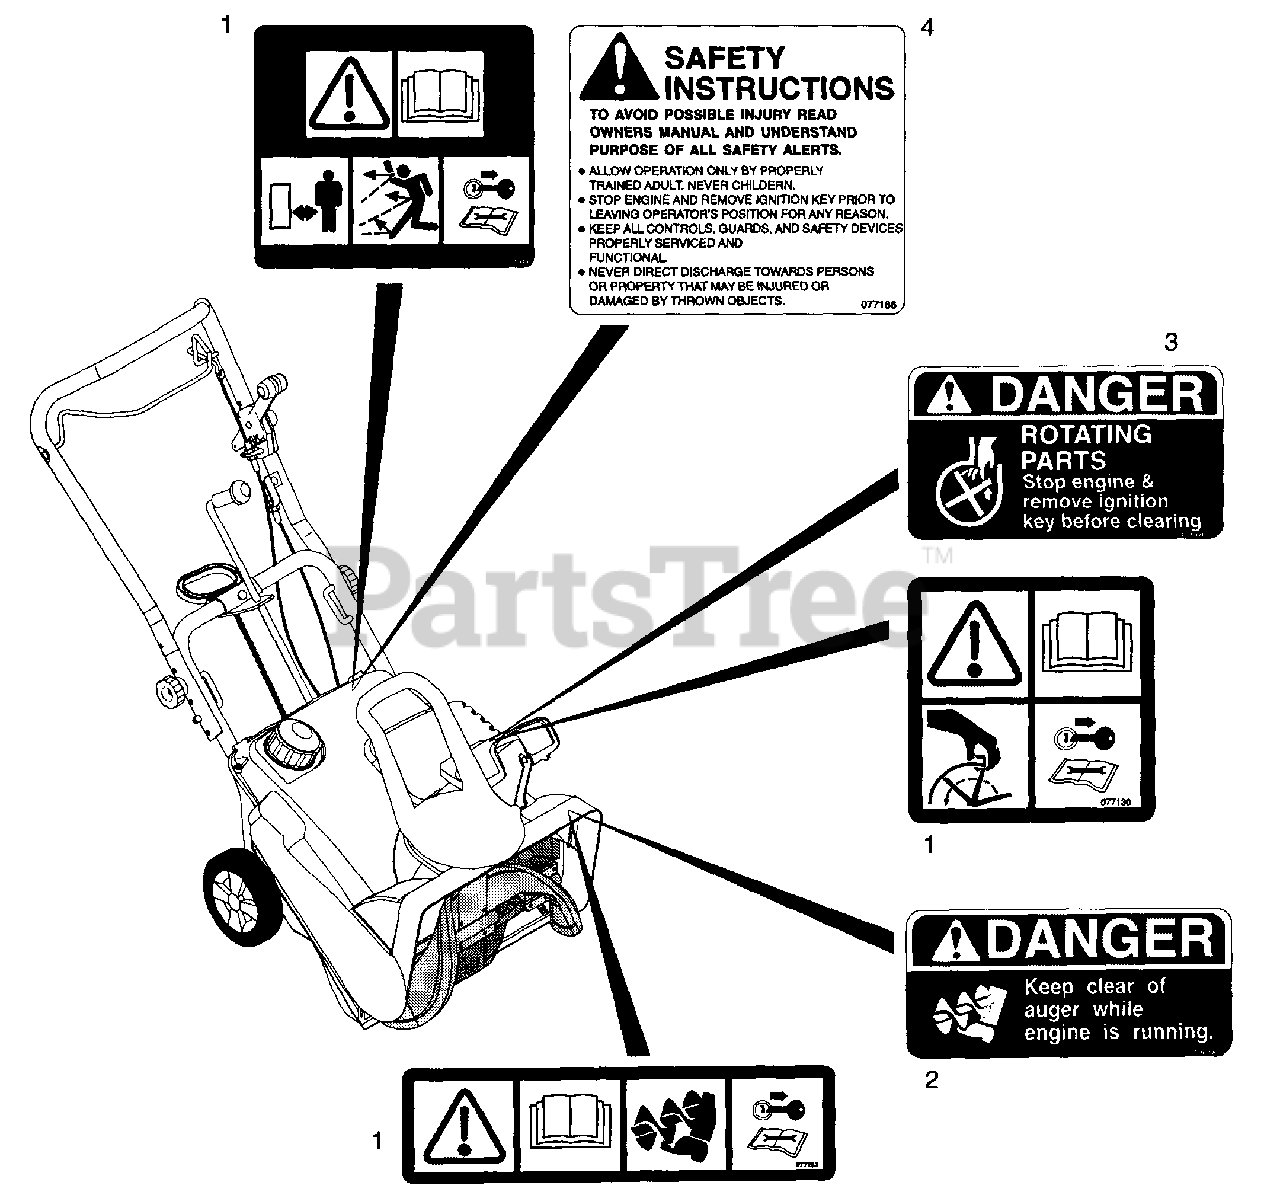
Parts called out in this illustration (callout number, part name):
1	DECAL SET-38000 SERIES-CE
2	DECAL - DANGER
3	DECAL-DANGER ROTATING PARTS
4	DECAL-SAFETY INSTRUCTION
